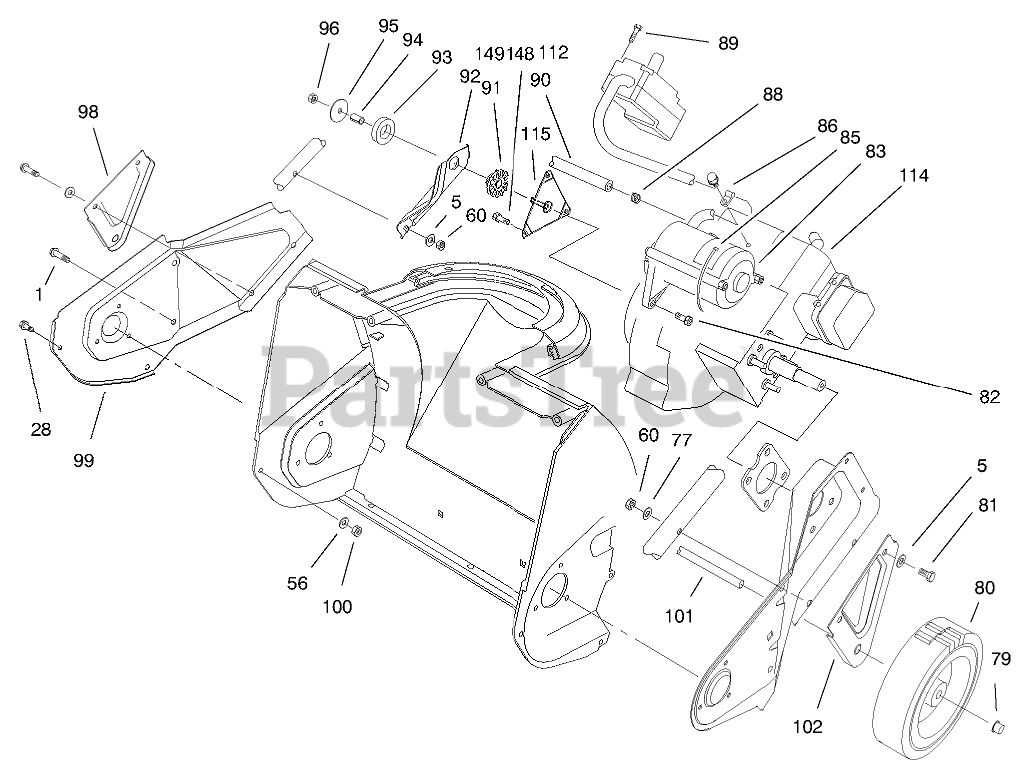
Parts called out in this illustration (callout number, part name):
1	SCREW-PLASTIC
5	WASHER-FLAT
56	WASHER-FLAT
60	NUT-LOCK, NI
77	WASHER
79	RETAINER-PUSH ON
80	WHEEL
81	SCREW-HH
82	SCREW-HH, TORX
83	ASM-Switch Housing
85	TIE-CABLE
86	CLAMP
88	CLAMP-HOSE
89	SCREW-PLASTITE
90	LINE-GAS
91	BUSHING-ISOLATOR
92	Support-Engine
93	Ring-Isolator
94	SPACER-TUBULAR
95	WASHER-FLAT
96	NUT-LOCK, NI
98	Bracket-Wheel
99	Sideplate-RH
100	NUT-LOCK, NI
102	Bracket-Wheel
112	SCREW X
115	BRACKET AND STUD ASM
147	Decal-Plate
148	SCREW
149	WASHER-LOCK / EXT
